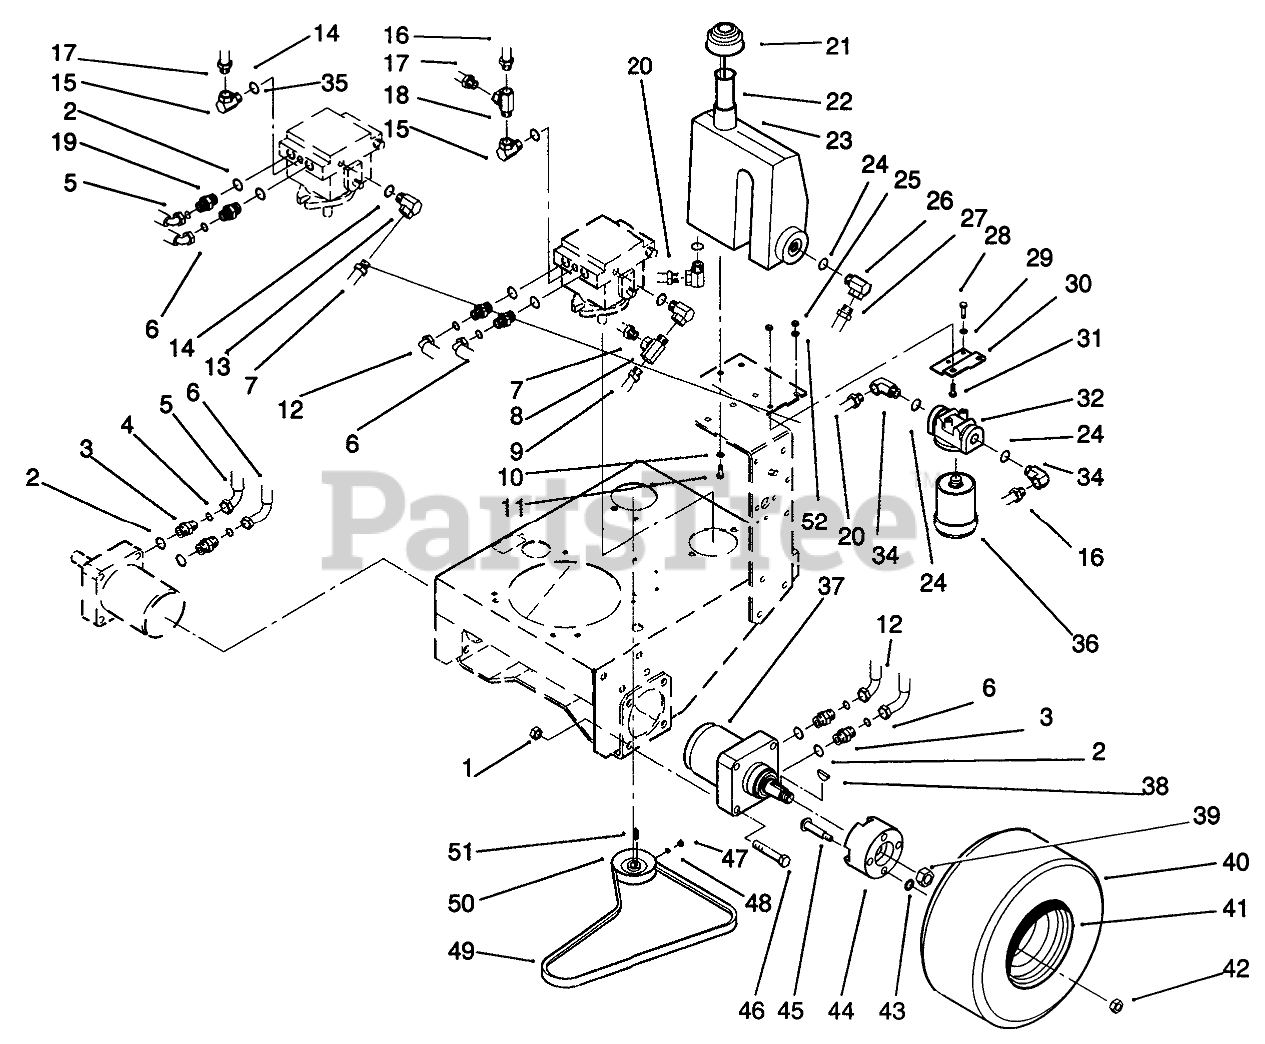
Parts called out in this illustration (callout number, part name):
1	NUT-LOCK, NI
2	FITTING-STR
3	FITTING-STRAIGHT
4	O-RING
5	HYDRAULIC HOSE ASM
6	HYDRAULIC HOSE ASM
7	HYD HOSE ASM
8	FITTING-HYD, TEE
9	HYDRAULIC HOSE ASM
10	WASHER-LOCK
11	SCREW-HH
12	HYDRAULIC HOSE ASM
13	FITTING-HYD, 90 DEG
14	O-RING
15	SWIVEL-PIPE, FEMALE
16	HYDRAULIC HOSE ASM
17	HYD HOSE ASM
18	FITTING-HYD, TEE
19	FITTING-STRAIGHT
20	HYD HOSE ASM
21	OIL CAP ASM
22	SCREEN-FILLER
23	Reservoir-Oil
24	O-RING
25	NUT-LOCK, NI
26	FITTING-HYD, 90 DEG
27	HYDRAULIC HOSE ASM
28	SCREW-HH
29	WASHER-LOCK
30	FILTER MOUNTING BRKTR
31	SCREW-HH
32	FILTER HD ASM
34	FITTING-HYD, 90 DEG
35	O-RING
36	CARTRIDGE-FILTER, OIL
37	WHEEL MOTOR ASM
38	KEY-WOODRUFF
39	Nut (Incl. w/Motor)
41	WHEEL
42	NUT-LUG
43	PUSHNUT
44	HUB-WHEEL
45	SCREW-HH
46	SCREW-HH
47	NUT-JAM
48	SCREW-SET
49	BELT-V
50	PUMP PULLEY
51	KEY-PUMP
52	WASHER-FLAT
